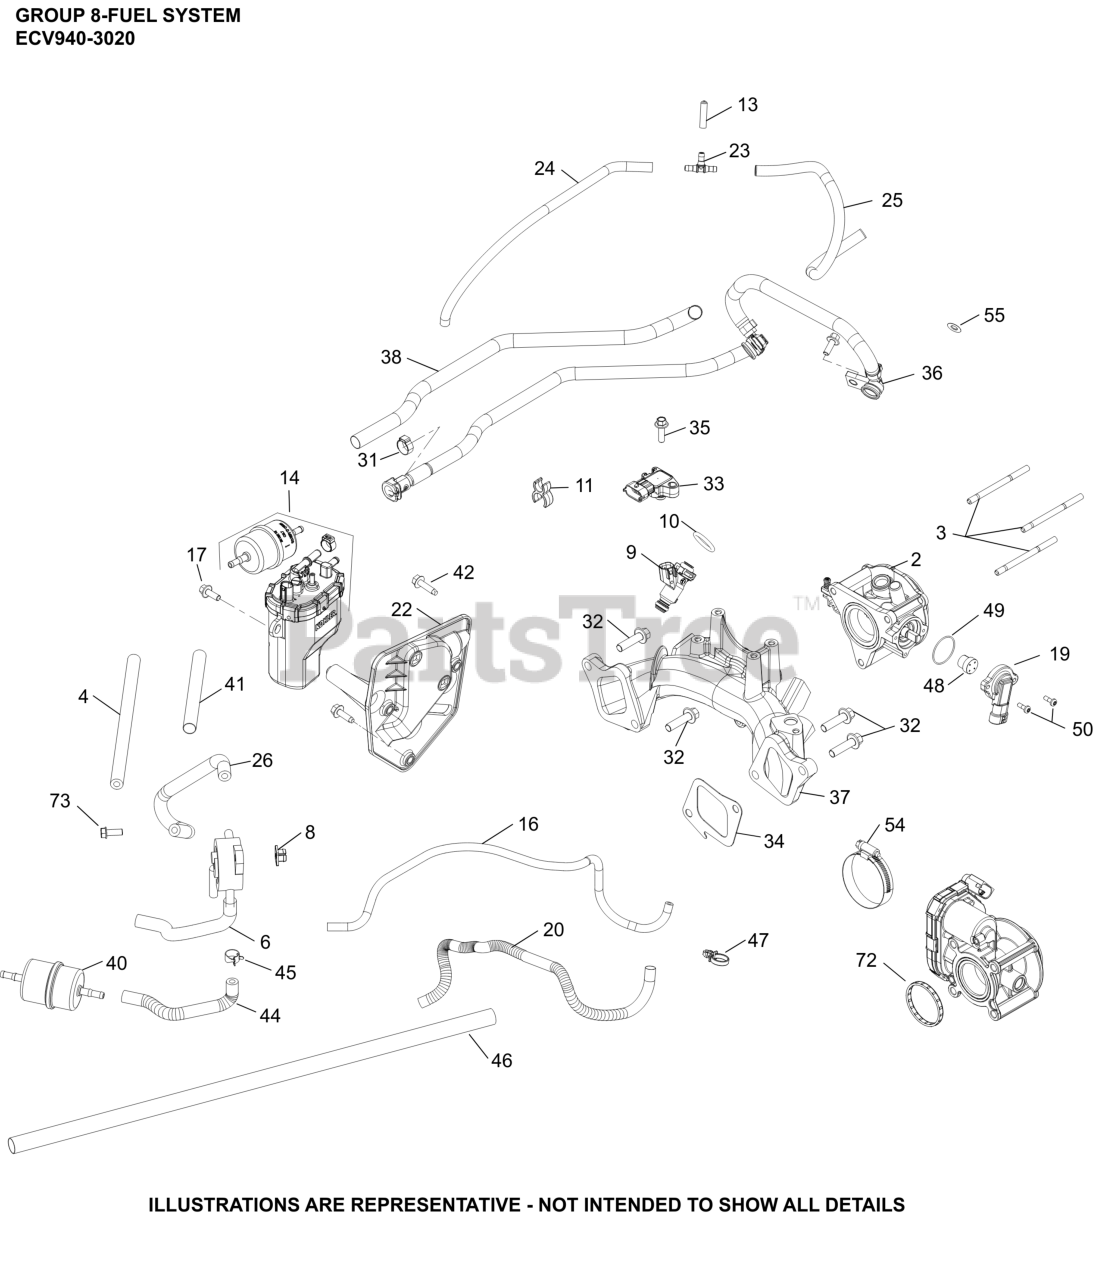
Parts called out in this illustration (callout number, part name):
2	BODY, THROTTLE ASM (30)
3	STUD,M6X1.0X84
4	LINE, FLEXIBLE FUEL
6	PUMP, FUEL
8	NUT, PLASTIC - BLACK
9	INJECTOR, FUEL
10	KIT, FUEL INJECTOR O-RING
11	RETAINER, CLIP
13	CAP, MASKING
14	KIT, FUEL PUMP MODULE
16	HOSE, EVAPORATIVE 20"- (#24326143S)
17	SCREW, FLG M6X1.0X16
19	SENSOR, THROTTLE POSITION
20	SLEEVE, ANTI-ABRASION
22	BAFFLE, V/S FUEL PUMP MODULE
23	TEE CONNECTOR
24	HOSE, EVAPORATIVE
25	SLEEVE, ANTI ABRASION
26	HOSE, FUEL LINE
31	CLAMP, HOSE
31	CLAMP, OETIKER
32	SCREW, FLG M8X1.25X30
33	SENSOR, T-MAP
34	GASKET, INTAKE MANIFOLD
35	SCREW, FLG M6x1.0x20
36	RAIL, FUEL ASSEMBLY (COMMAND PRO 999)
37	MANIFOLD, INTAKE EFI - VERTICLE
38	SLEEVE, ANTI ABRASION
40	FILTER, FUEL
41	SLEEVE, ANTI ABRASION -USE 25 431 12-S
42	SCREW, THREAD FORMING
44	HOSE,LW PERM.FUEL 24.00"-USE 25 111 81-S
45	SPRING CLAMP, HOSE
46	SLEEVE, HEAT REFLECTIVE
47	CLIP, FUEL LINE
48	MAGNET ASSEMBLY, TPS
49	O-RING, TPS SENSOR
54	CLAMP, HOSE-USE 25 237 21-S
55	CLIP, RETAINER
72	O-RING, THROTTLE BODY
73	SCREW, HEX HEAD
